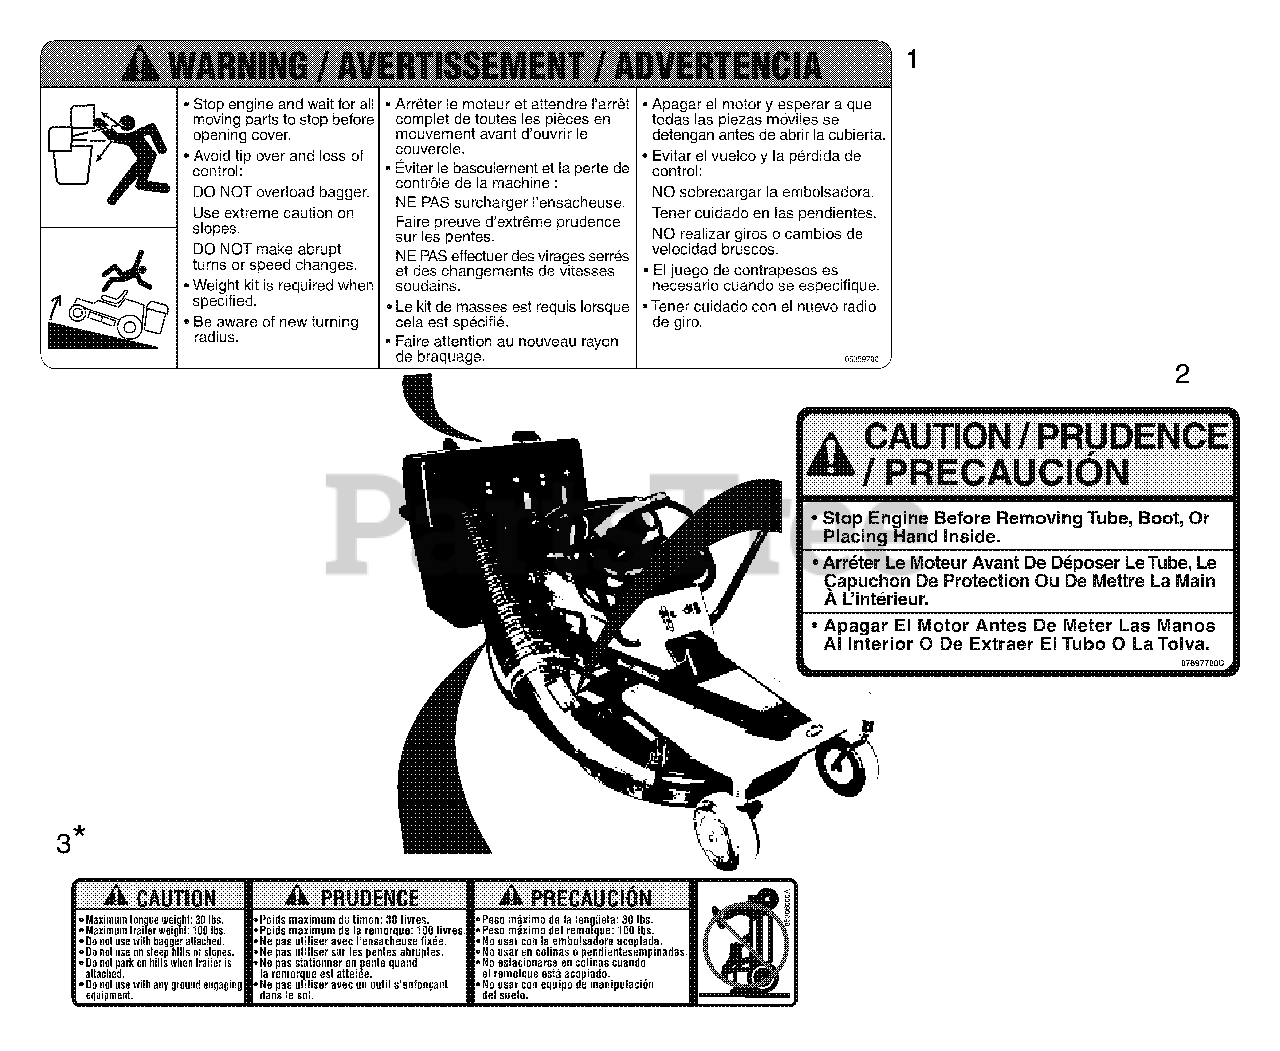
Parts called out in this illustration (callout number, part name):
1	DECAL, BAGGER COVER
2	DECAL-BOOT CAUTION
3	DECAL-HITCH 100#
